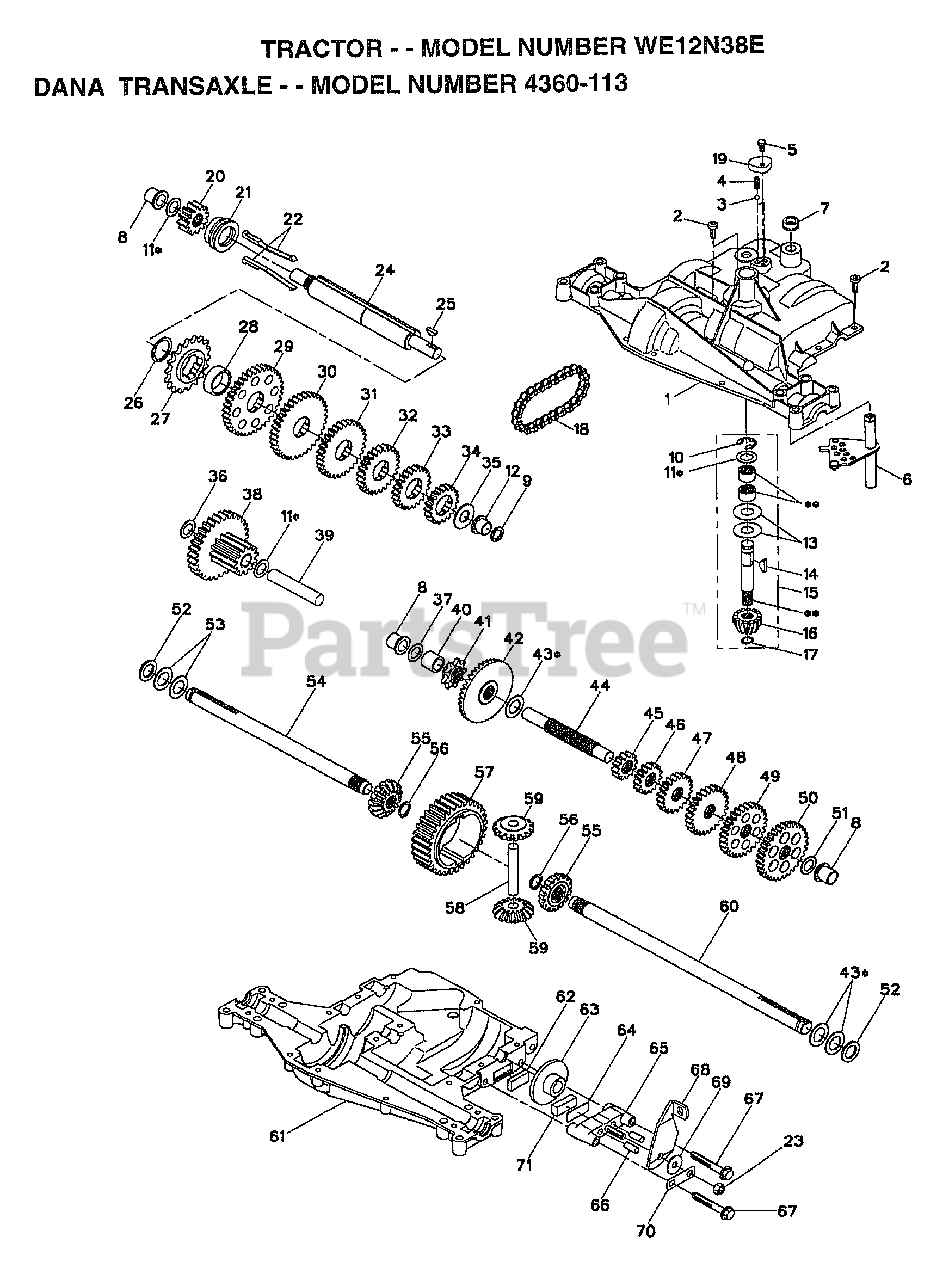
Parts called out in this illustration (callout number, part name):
1	HOUSING.UPPER.DANA.(5305J)
4	"SPRING, DETENT LT"
5	SCREW.TAPPING.1/4-20X.734
6	KIT SHIFTER ASM
9	SEAL.OIL.DAN.5508
10	RETAINING RING LT
11	ASM KIT SHIM 4689
12	BEARING.FLNG.5511
13	WASHER T
14	KEY WOODRUFF-DANA
15	AS KIT INPUT SHFT
16	PINION 14T T
17	"RING,RETAINING LT"
18	"CHAIN,24 PTCH LT"
19	COVER.DETENT.(5584)
20	GEAR.SPUR.12T.(5627)
21	CLUTCH.COL.5467
22	ASM KIT CLTCH KEY
23	NUT.LOCK.5/16-24
24	SHAFT INTERM DANA
25	WOODRUFF KEY
26	"RING,RETAINING LT"
27	SPROCKET 18T T
28	SPACER YT
29	GEAR SPUR 37 TTH
30	GEAR SPUR 35 TTH
31	GEAR SPUR 30T
32	GEAR 25T LT
33	GEAR SPUR 22 TT
34	SPUR GEAR 19T
35	"WASHER, PLAIN LT"
36	WASHER 045
37	WASHER 031
38	ASSY.GEAR.6153 12T&30T
39	SHAFT IDLER
40	SPACER T
41	SPROCKET 9T LT
43	ASM KIT SHIM
44	SHAFT T
45	GEAR SPUR 12 TTH
47	GEAR SPUR 20T
48	"GEAR, SPUR 25T LT"
49	GEAR 28T T
50	"GEAR, SPUR 31T LT"
51	WASHER 060
52	NEOPRENE WASHER
53	WASHER 031
54	AXLE.LH(5528-1)
55	GEAR 15T T
56	RING.RETAINING.(5270)
58	SHAFT T
59	GEAR 1ST T
60	AXLE.RH.(5528-2) DANA
61	HOUSING LOWER TNS
62	PUCK T
63	BRAKE DISC. T
64	SPACER LT
66	PIN T
67	SCREW.(5562) .5/16-18X2.35
69	WASHER LT
70	BRACKET, ANTI-ROTATION
71	PUCK T
